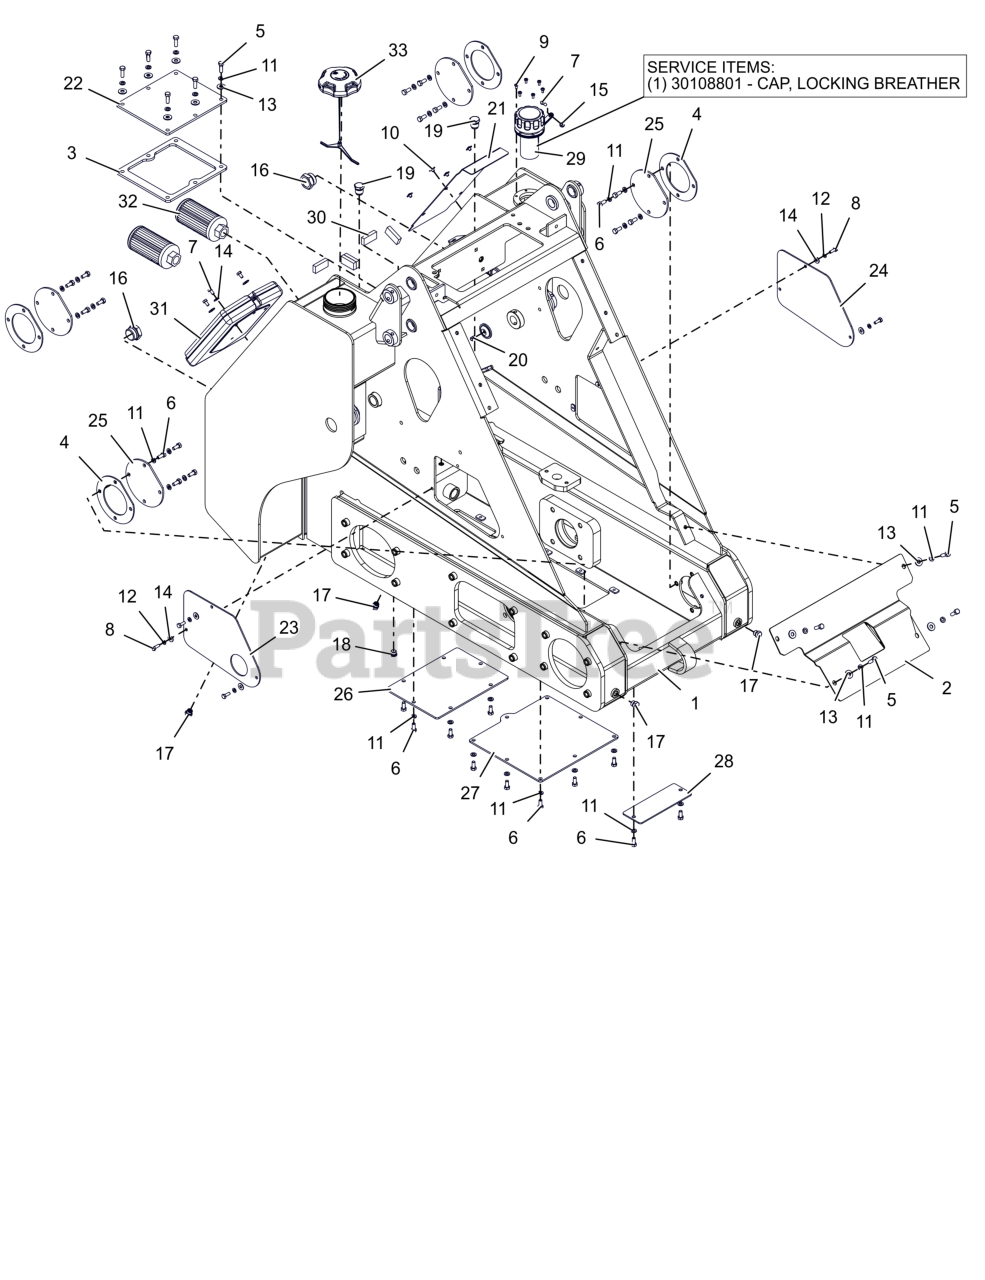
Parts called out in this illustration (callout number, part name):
1	FRAME, MAIN - W/SAFETY DECALS
2	COVER, FRONT - BATTERY
3	GASKET- OIL TANK
4	GASKET, AXLE COVER
5	BLT,HEX .31-18X1.00 G5 ZCC
6	BLT,HEX .31-18X.75 G5 ZCC
7	BLT,HEX .25-20X.50 G5 ZCC
8	BLT, HEX .25-20X.75 G5 ZCC
9	SCR, MCH 10-32 X .375 PH ZCC
10	SCR,BTNHD .25-20X.50 ZCC
11	WSHR,LK-REG .312X.078 ZCC
12	WSHR,LK-REG .250X.062 ZCC
13	WSHR,FLT .375X.875X.083 ZCC
14	WSHR, FLT .312X.734X.065 ZCC
15	NUT,NYL .25-20 G5 ZCC
16	WINDOW, SIGHT - FLUID LEVEL
17	PLUG, HEX - .56 ORB
18	PLUG, HEX - CSK .56 ORB
19	PLUG, VENT
20	PLUG,PIPE .12 SQ HD UNFIN STL
21	COVER, FILTER (RED)
22	COVER, OIL TANK (RED)
23	COVER, SIDE RH (RED)
24	COVER, SIDE - LH (RED)
25	COVER, AXLE TRANSMISSION (RED)
26	COVER, ACCESS REAR (BLACK)
27	COVER, ACCESS CENTER (BLACK)
28	COVER, ACCESS FRONT (BLACK)
29	BREATHER, LOCKING
29	CAP, LOCKING BREATHER
30	MAGNET, HYD - OIL TANK
31	BOX, MANUAL
32	FILTER, HYD - INTAKE .75 NPT
33	CAP, DIESEL FUEL 3.5"
